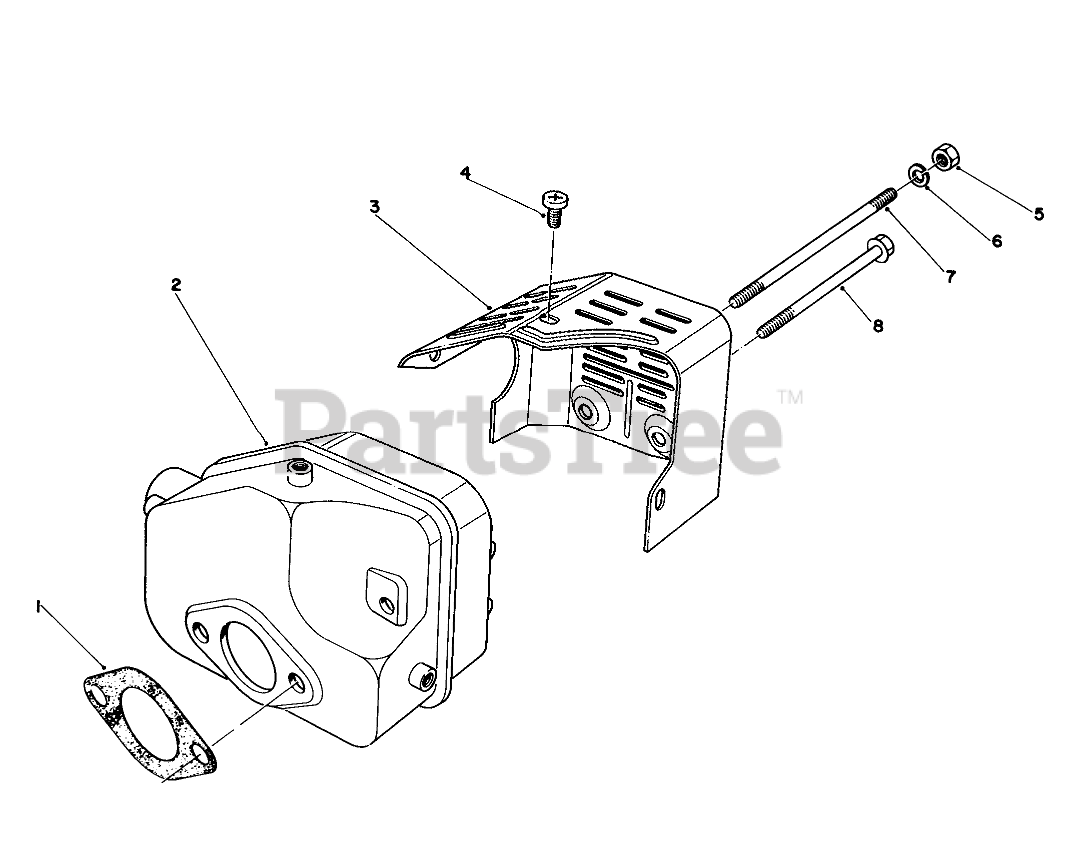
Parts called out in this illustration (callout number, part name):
1	GASKET
2	Muffler
3	COVER
4	SCREW
6	WASHER-LOCK
